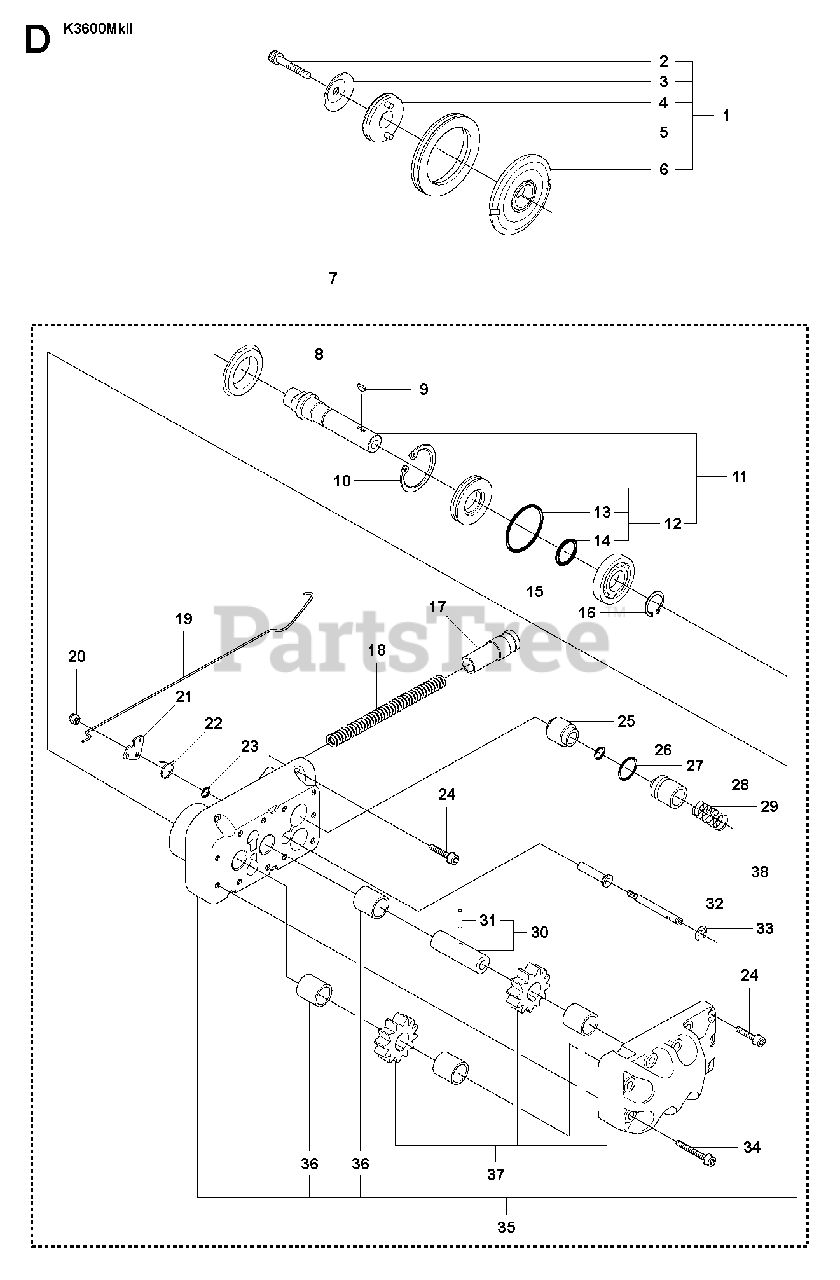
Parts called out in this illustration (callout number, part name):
1	GEAR WHEEL ASSYIncl. 2, 3, 4, 5, 6
7	HYDRAULIC MOTORIncl. 8-11,
9	WOODRUFF KEY
20	HEXAGON LOCKING NUT
24	SCREW IHSCFM
34	SCREW IHSCFM
